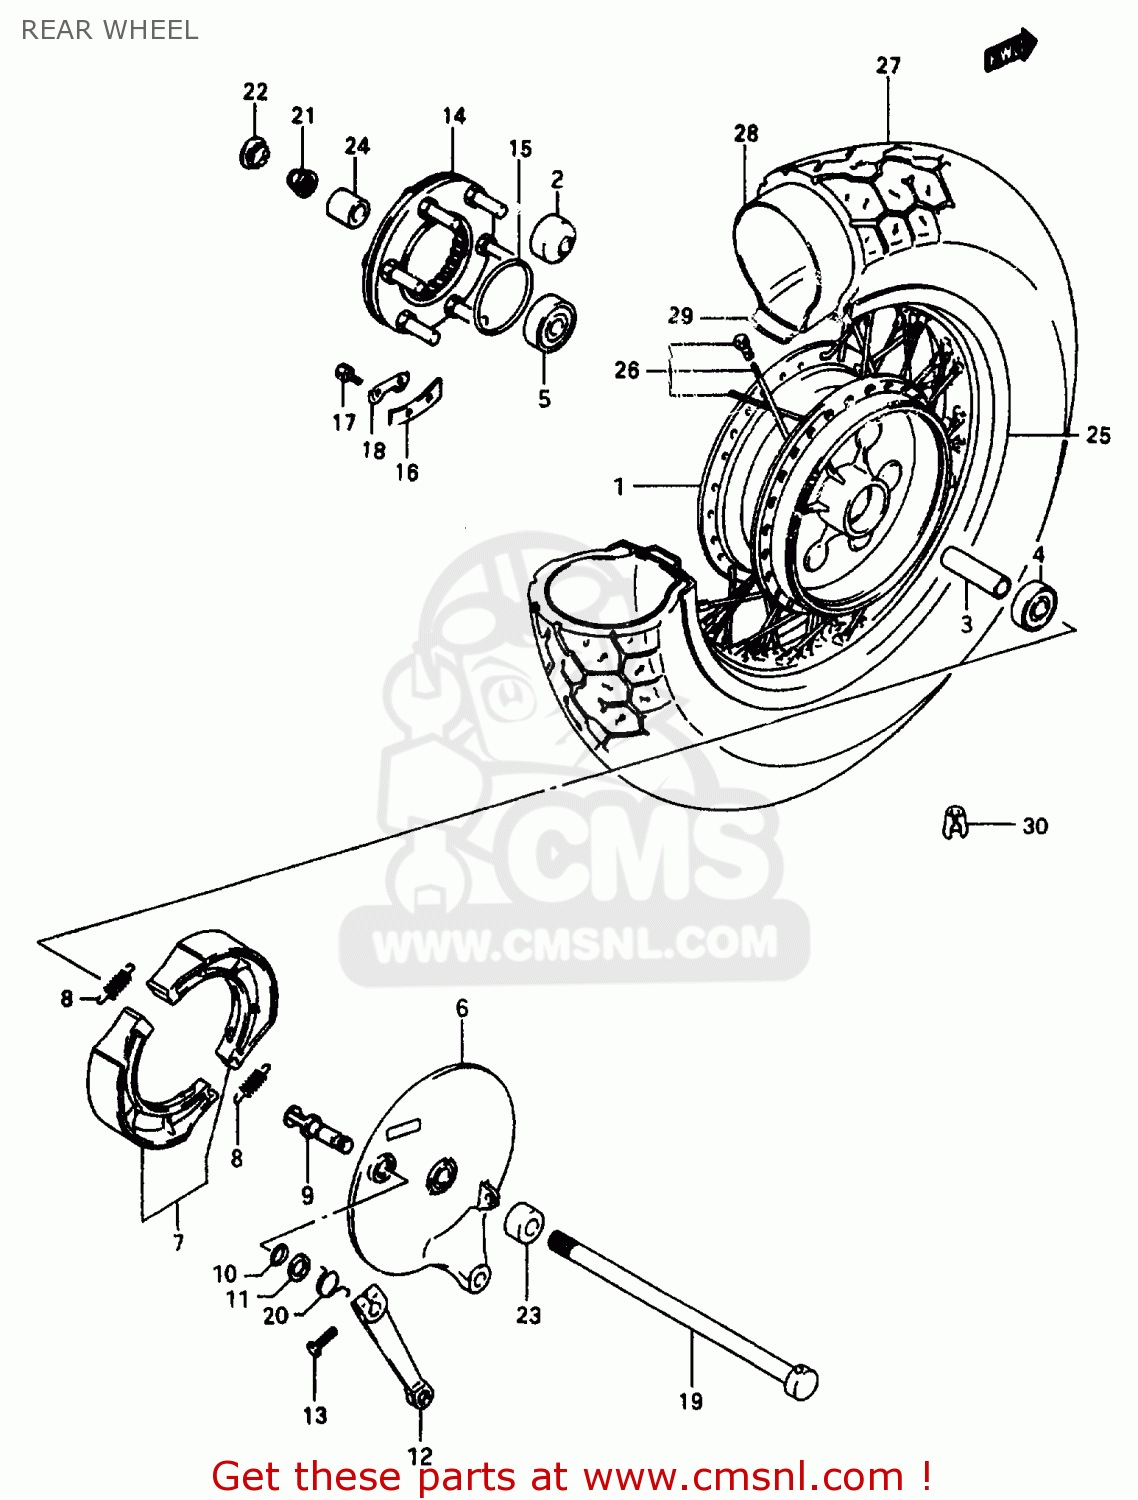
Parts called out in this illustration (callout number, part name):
1	HUB SET,REAR
2	BUSH
3	SPACER(17.5X25X80)
4	BEARING
5	BEARING
6	PANEL,REAR BRAKE ANCHOR
7	SHOE SET,BRAKE (NAS)
8	SPRING,BRAKE SHOE
9	CAM,RR BRAKE
10	O RING(D:2.4,ID:14.8)
11	WASHER (15X24X1.6)
12	LEVER,RR BRAKE CAM
13	BOLT
14	JOINT ASSY,RR HUB DRIVEN
15	O RING(D:2.1,ID:65)
16	WASHER,THRUST(T:1.6)
17	BOLT(6X16)
18	WASHER
19	AXLE,RR
20	SPRING
21	NUT
22	CAP,RR AXLE,R
23	SPACER,REAR AXLE,RIGHT
24	SPACER,RR AXLE,L
25	RIM, WHEEL (MT3.00X15 M/C)
26	SPOKE ASSY,RR WHEEL
27	TIRE,REAR 140/90-15M/C
28	TUBE ASSEMBLY,WHEEL,INNER
29	PROTECTOR,WHL INR TUBE
30	BALANCER,WHEEL
